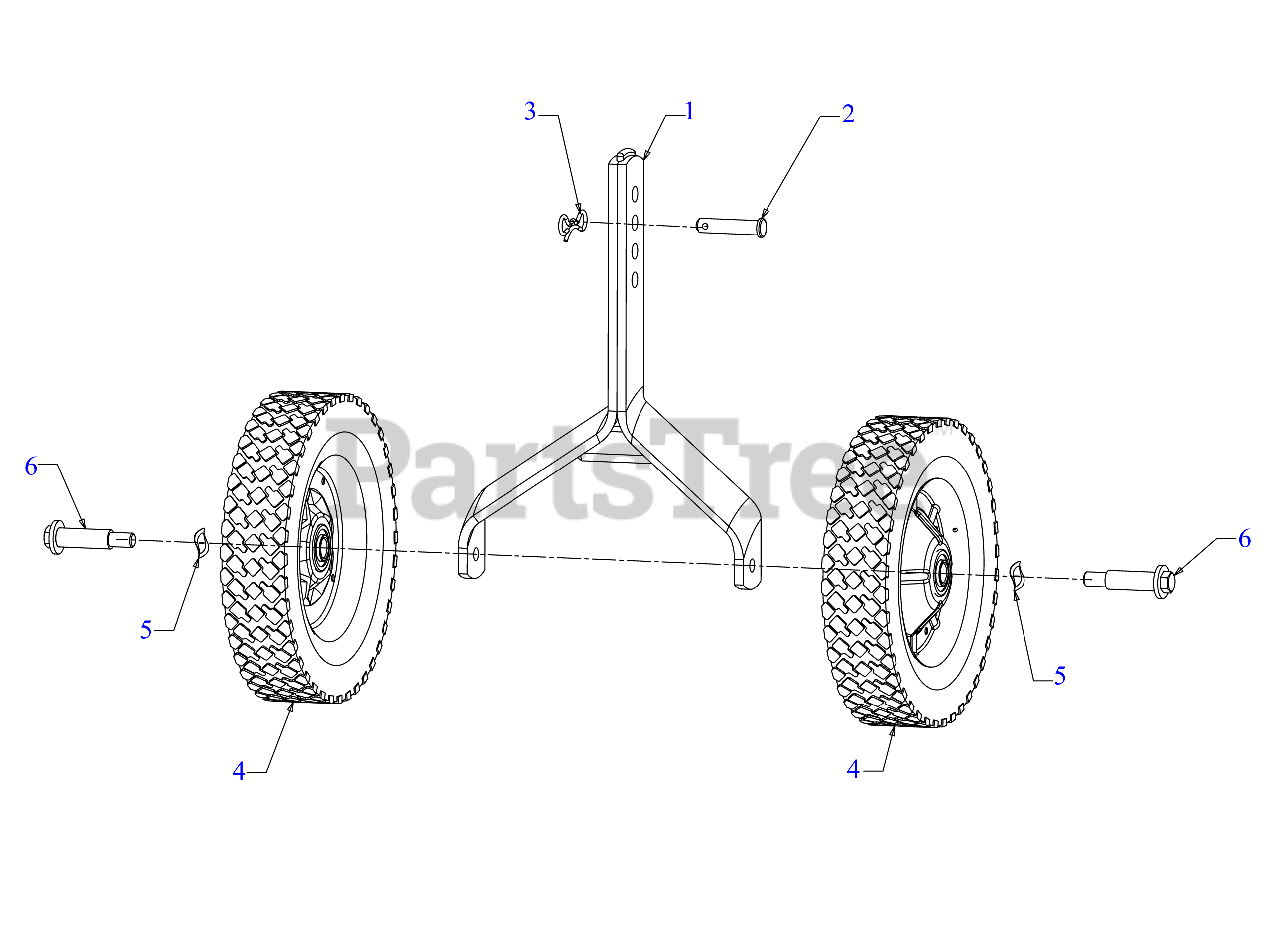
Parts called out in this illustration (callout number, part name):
1	WHEEL BRACKET ASSEMBLY (POWDER BLACK)
2	CLEVIS PIN 3/8 x 1.620
3	PIN:COTTER
4	COMPLETE WHEEL 8 x 1.75 CRAFTS GRY
5	WAVE WASHER
6	SHOULDER SCREW .496X1.44 3/8-16
